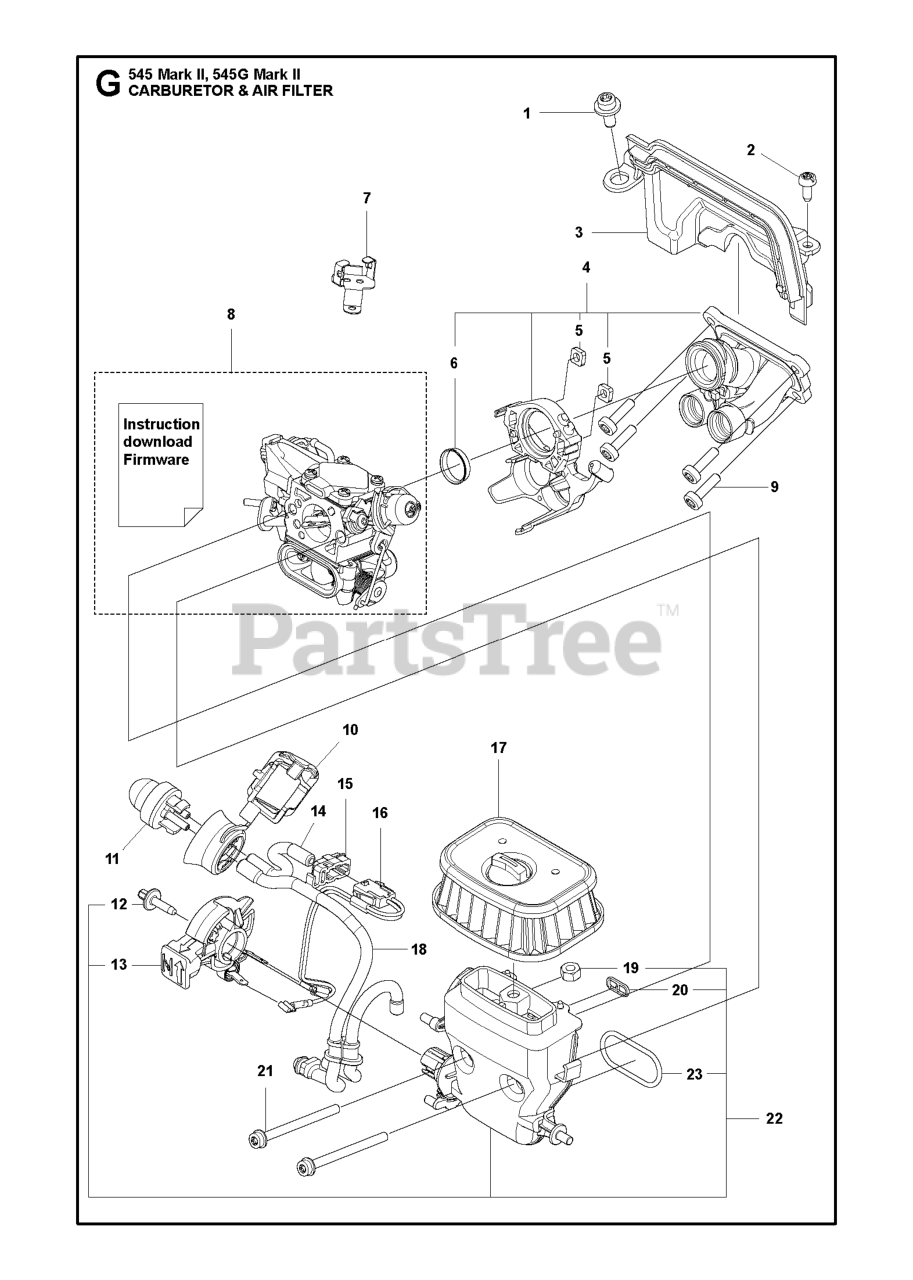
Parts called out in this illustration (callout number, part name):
1	SCREW ITXSCM WASHER M5X12 T27
3	INSULATION WALL
4	INLET PIPE ASSY
6	SUPPORT SLEEVE
7	RETAINER CONTACT CLAMP
8	CARBURETTOR KIT AT-15 H545/545
9	SCREW ITXSCM M4X15 T27 12.9 T
11	AIR PURGE BUBBLE
13	CHOKE CONTROL ASSY CHOKE/STOP
15	CONTACT CLAMP
16	WIRING ASSY STOP
17	AIR FILTER ASSY MESH 25 MICRON
17	AIR FILTER ASSY MESH NW
17	AIR FILTER ASSY MESH 64 MICRON
18	FUEL HOSE PURGE/TANKVENTILATIO
21	SCREW ITXSCFM M4X50 T20 12.9
22	FILTER HOLDER ASSY
